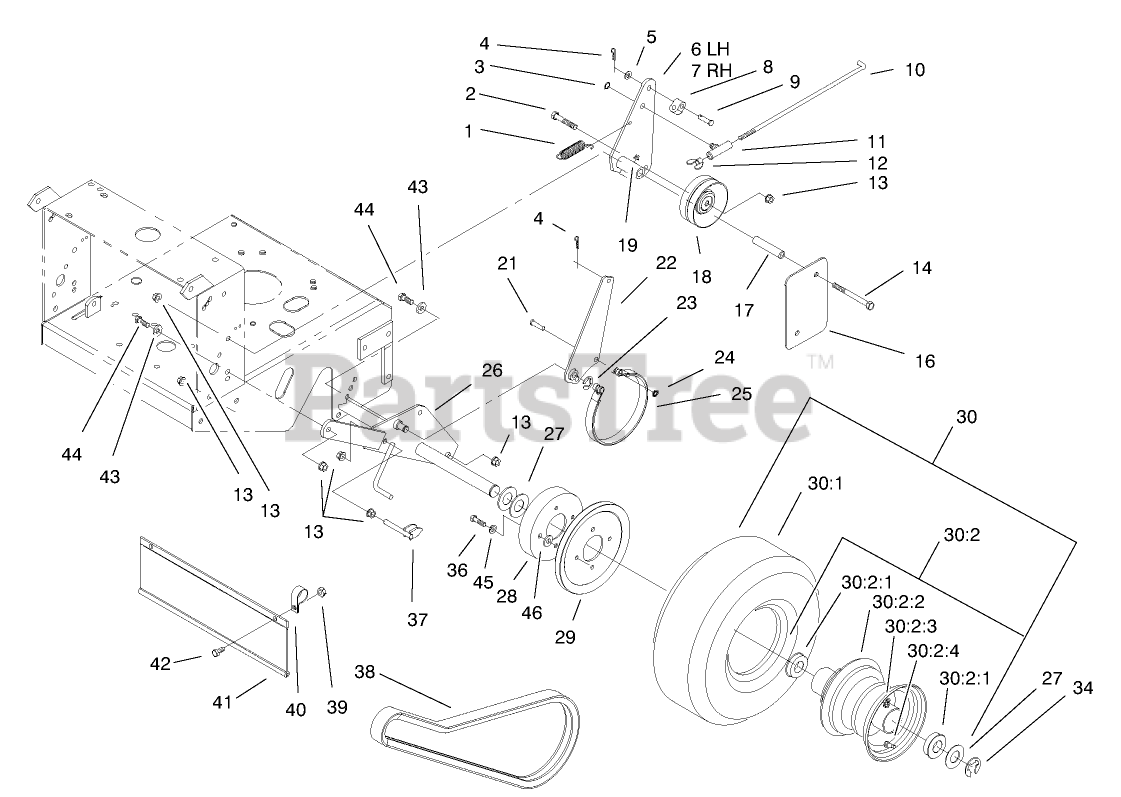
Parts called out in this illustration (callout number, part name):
1	SPRING-EXTENSION
2	SCREW-HH
3	RING-RETAINING
4	PIN-COTTER
5	WASHER-PLAIN
6	RH IDLER ARM ASM
7	LH IDLER ARM ASM
8	FITTING-ROD
9	PIN-CLEVIS
10	ROD-BRAKE
11	SWIVEL-BRAKE
12	WINGNUT-NYLOCK
13	NUT-HHF, WHIZ
14	SCREW-HH
16	SHIELD-WHEEL, DRIVE
17	SPACER-SHIELD
18	IDLER-DRIVE, WHEEL
19	FITTING-GREASE
21	PIN-CLEVIS
22	ARM-BRAKE
23	RING-RETAINING, EXTERNAL
24	NUT-PUSH
25	BAND-BRAKE
26	AXLE ASM
27	WASHER-SPACER
28	DRUM-BRAKE
29	SHEAVE-WHEEL, DRIVE
30	WHEEL AND TIRE ASM
30:2	WHEEL AND HUB ASM
30:2:1	BEARING-FLANGED
30:2:2	Rim ASM
30:2:3	Fitting-Grease
30:2:4	Valve Stem and Cap
34	RING-SNAP
36	SCREW-HH
37	Scraper
38	BELT-DRIVE, WHEEL
39	NUT-LOCK, NI
40	CLAMP-R
41	SHIELD-TRAILING
42	SCREW-HH
43	WASHER-BELLEVILLE
44	SCREW-HH
45	WASHER
46	WASHER-LOCK
